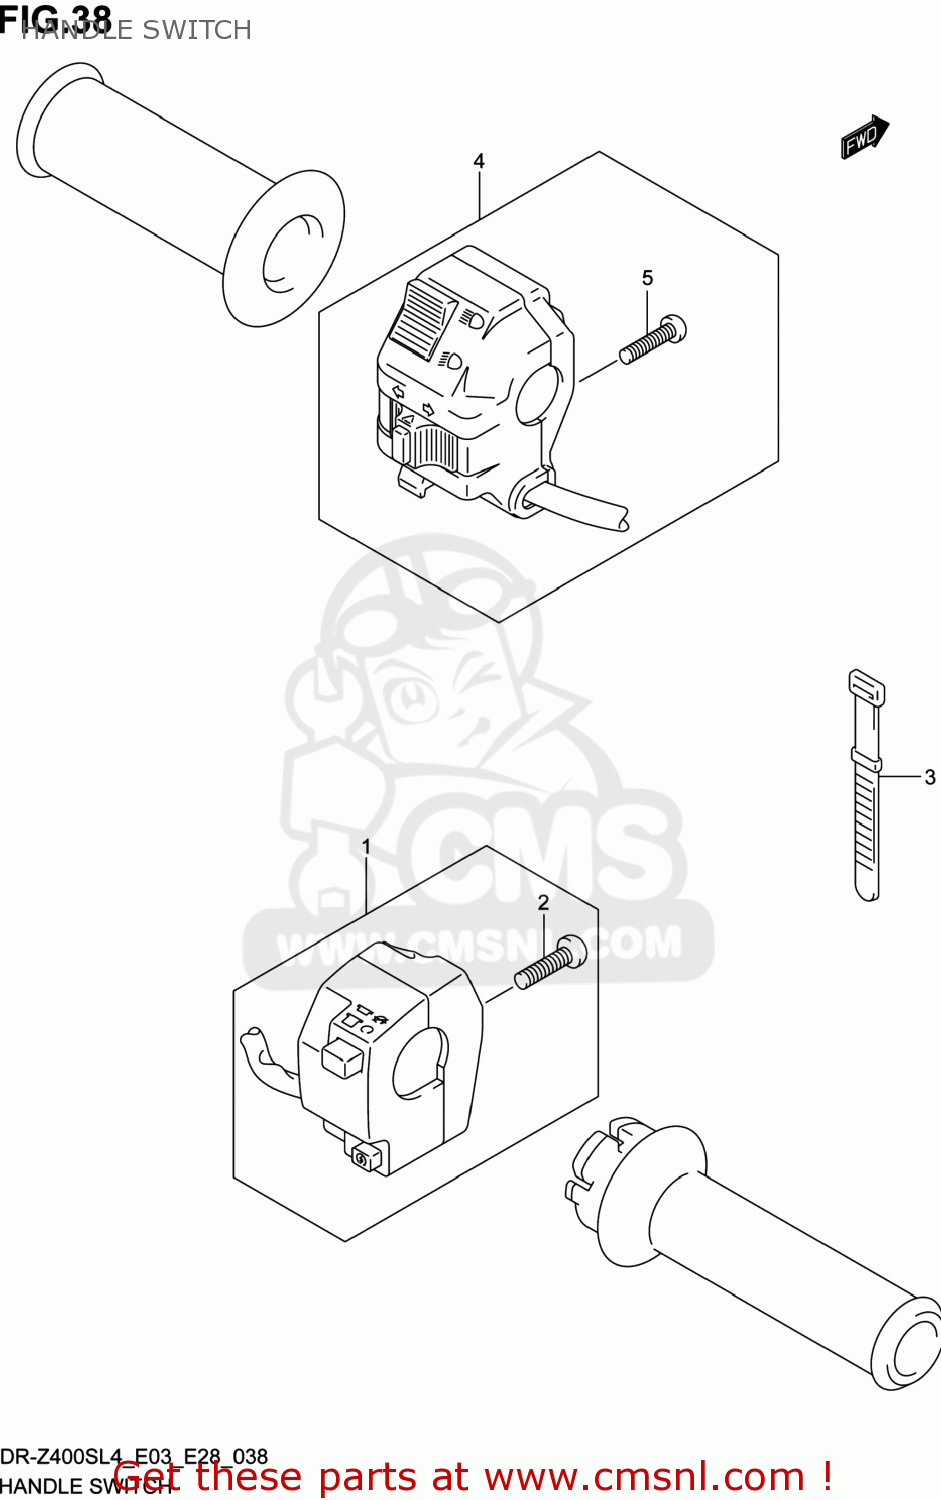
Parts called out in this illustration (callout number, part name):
1	SWITCH ASSY,HANDLE,R
2	SCREW
3	CLAMP(L:120)
4	SWITCH ASSY,HANDLE,L
5	SCREW
